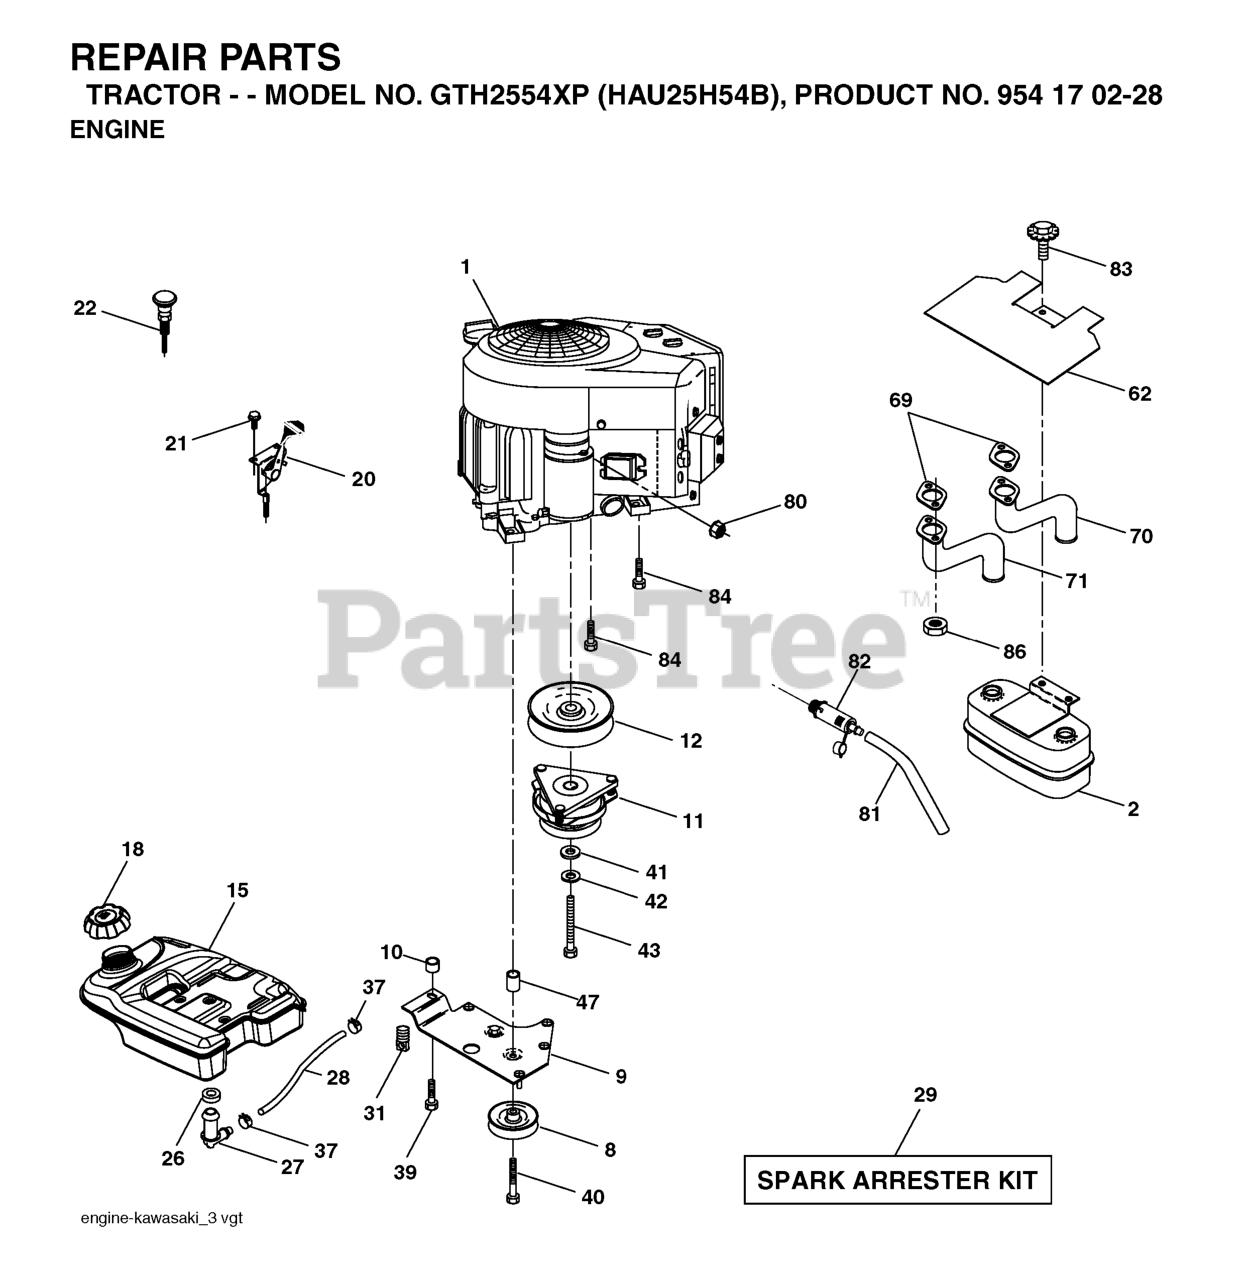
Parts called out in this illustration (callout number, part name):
2	MUFFLER.TWIN.CYL.LOW.TONE
8	RP.IDLER GROOVED
9	KEEPER ASM BELT ENGINE
11	CLUTCH MZ ZTR GT.48/54"1.125"
12	PULLEY ENG VGT ELECT CLUTCH
15	TANK.FUEL.5.0 LEFT.FILL.YTGT
18	TANK CAP
20	CONTROL.THROTTLE.COBRA.42"BLK.
21	SCREW
22	CONTROL, CHOKE
26	BUSHING OUTLET T
27	STEM FUEL TANK
28	HOSE
29	KIT.SPARK ARRESTOR 794945 B&S
37	HOSE CLAMP
39	SCREW TT 3/8-16X2-1/4 UNC
40	Screw TT 3/8-16 x 4 unc
42	LOCKWASHER
43	BOLT HEX 7/16-20 X 3.75 GR. 5
62	HEAT SHIELD
70	TUBE.EXHAUST.KAWASAKI.RH
71	TUBE EXHAUST LH
80	FLANGE NUT
81	TUBE, DRAIN OIL ASM.
83	BOLT.5/16-18UNCX3/4 W/SEMS.BLK
84	SCREW 3/8-16 X 1-1/2
86	NUT.HEX.FLANGE.TOPLOCK
